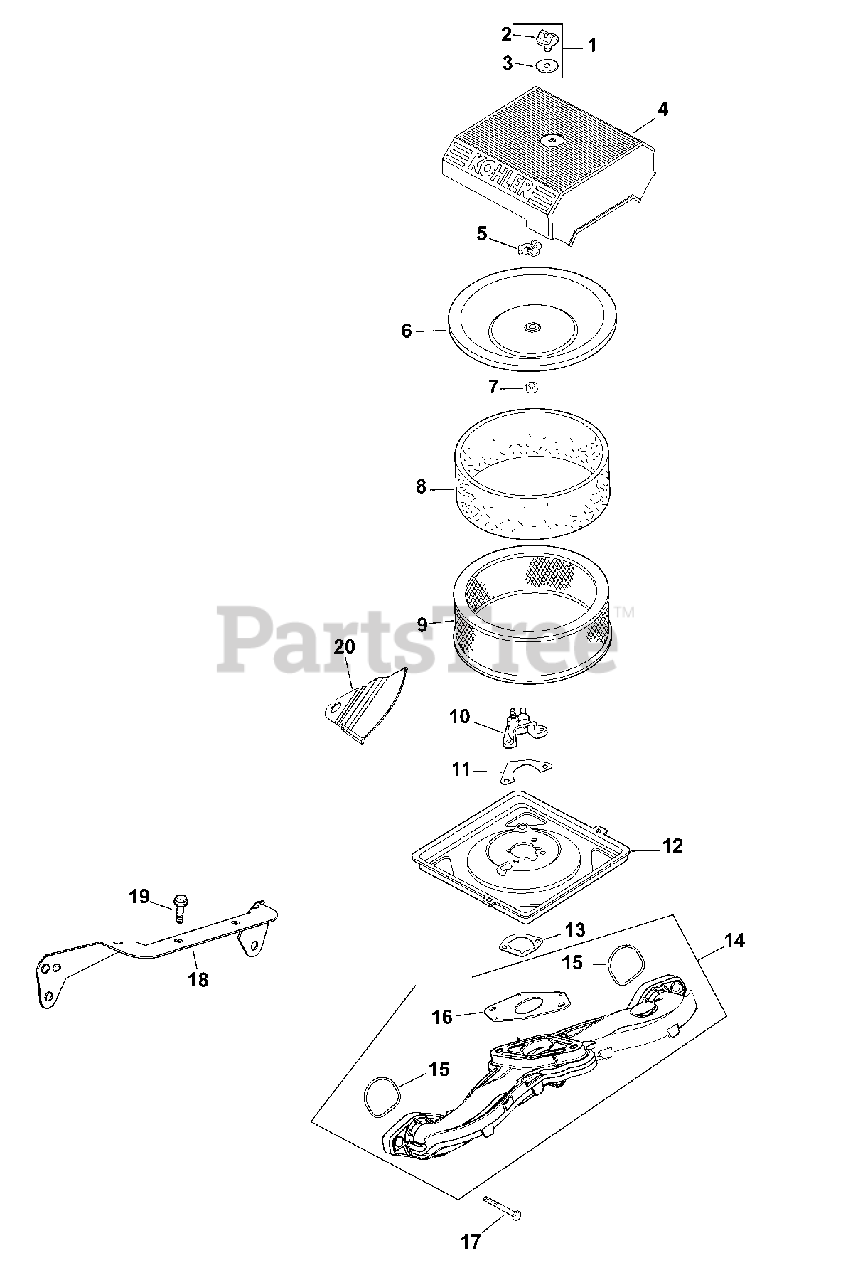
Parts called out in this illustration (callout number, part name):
1	KIT, KNOB W/SEAL
2	KNOB, AIR CLEANER COVER-USE 25 341 04-S
4	COVER, AIR CLEANER - DISCONTINUED
5	NUT, WING
6	COVER, INNER AIR CLEANER
7	SEAL, BREATHER
8	PRE-CLEANER (HIGH)
9	ELEMENT, AIR FILTER (HIGH) - Also available Retail Packaged 24 883 03-S1 Air Filter Kit
10	CUP, SPITBACK W/STUD-USE 24 109 25-S
11	GASKET, FUEL SPITBACK CUP
12	BASE, AIR CLEANER-USE 24 094 82-S
13	GASKET, AIR CLEANER BASE
14	MANIFOLD, INTAKE - PLASTIC-USE 24 164 91
15	O-RING, INTAKE PORT
16	GASKET, CARBURETOR
17	SCREW, FLG M6X1.0X40
18	BRACKET, AIR CLEANER BASE
19	SCREW, FLG THD FRM M5X.8X10
20	BAFFLE, SPIT-BACK CUP-USE 24 063 105-S
